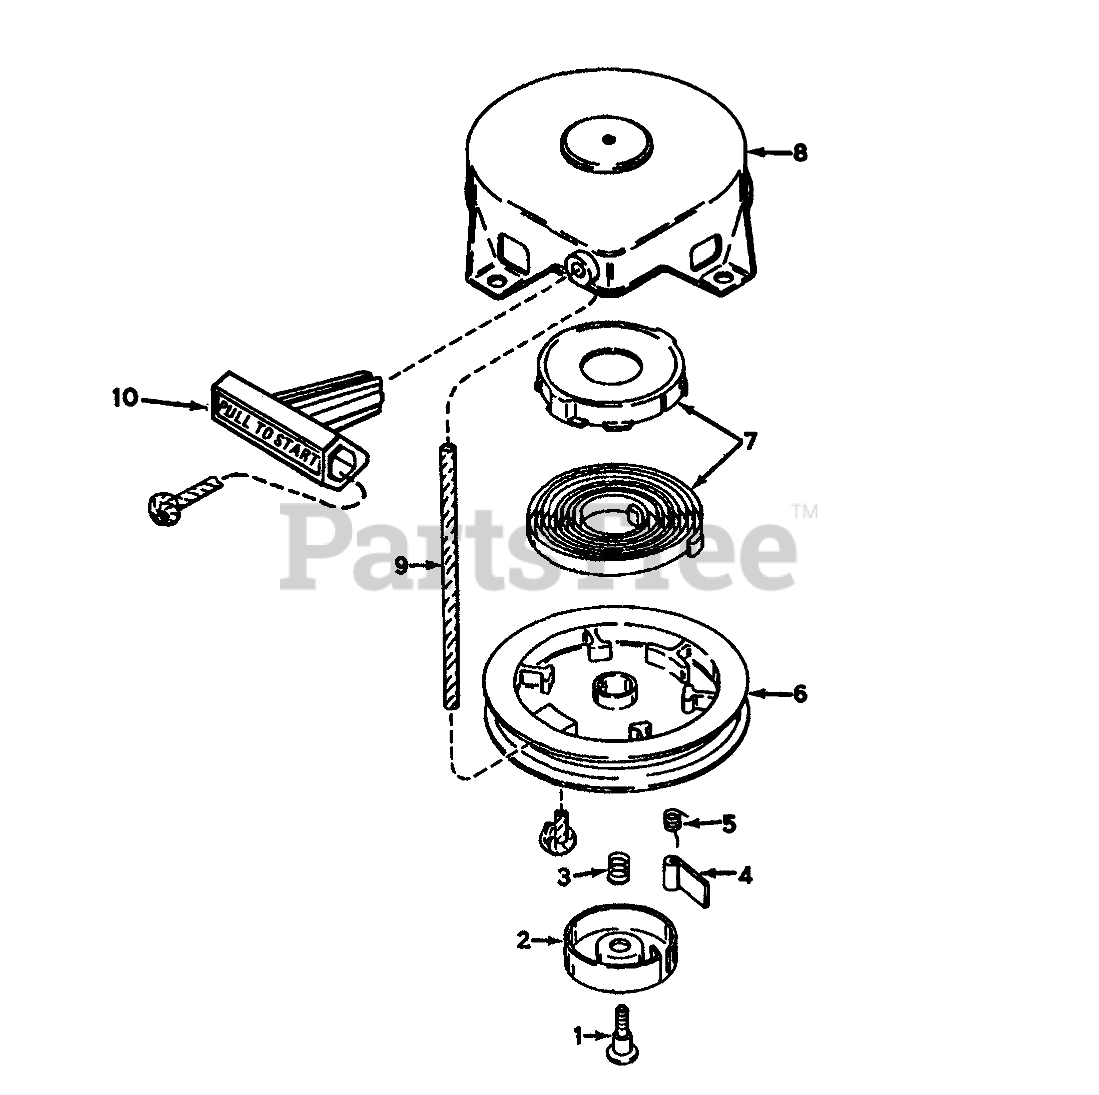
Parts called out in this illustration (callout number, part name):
2	Retainer
3	Spring-Brake
4	Dog-Starter
5	Spring-Dog
7	Spring & Keeper Assy
8	Housing-Starter
9	Rope-Starter (98 cut to length)
10	Handle-Starter
